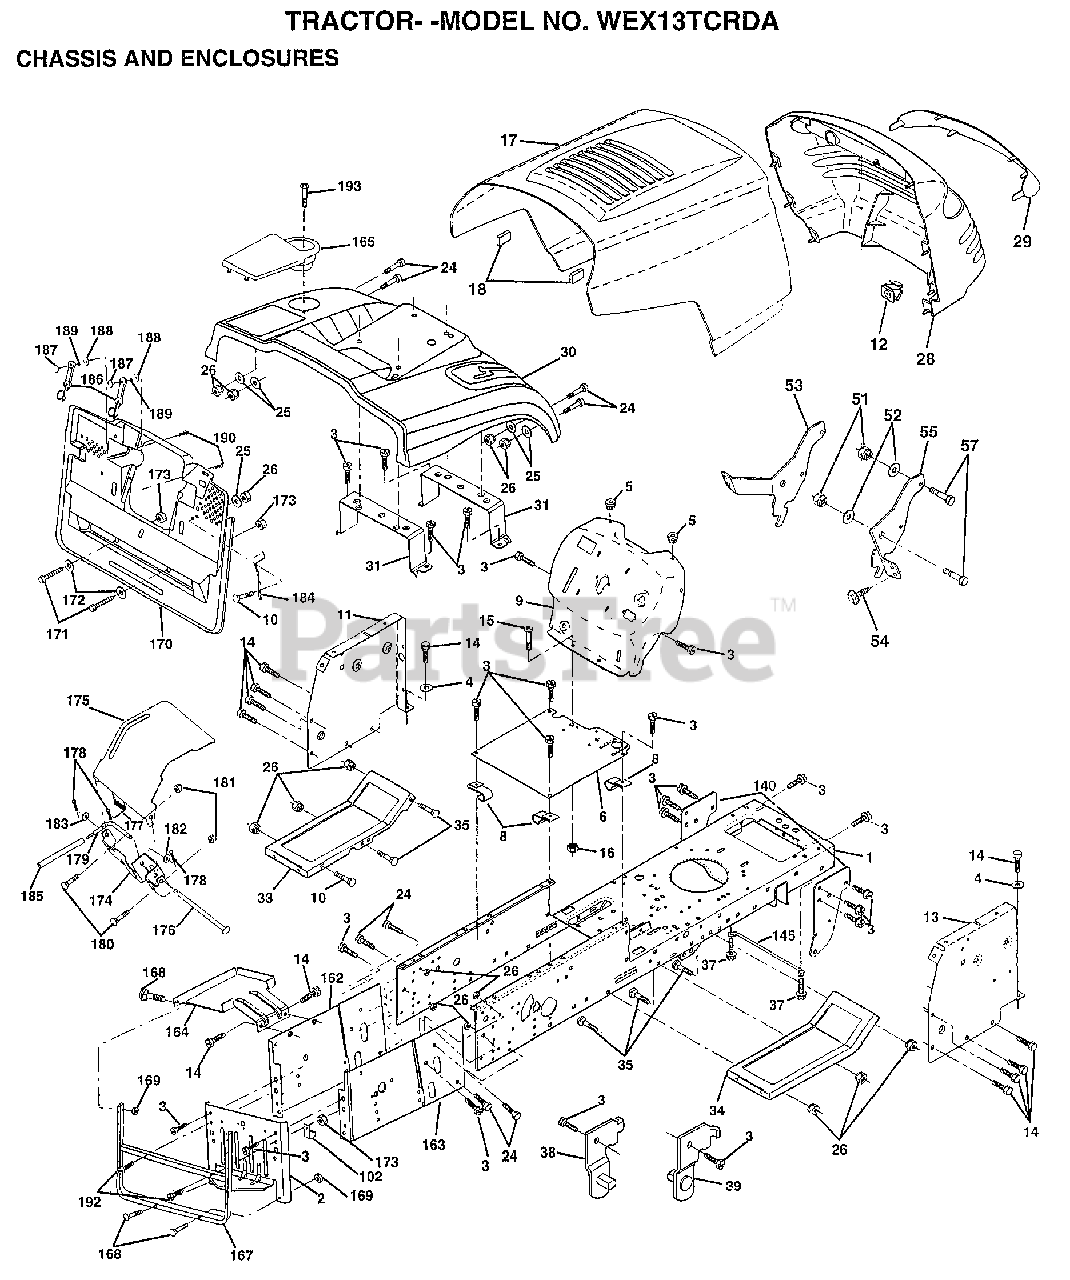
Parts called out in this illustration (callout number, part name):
1	CHASSIS.STAMPING
2	DRAWBAR.CRD
3	SCREW
4	WASHER
5	BUMPER-HOOD/DASH
6	SADDLE
8	"CLIP,INSULATOR"
9	DASH.SILKSCREEN
11	"PANEL-DASH,LH"
12	CLIP.TINNERMAN
14	SCREW LT
15	SCREW
17	HOOD.STEEL.ASSY
24	BOLT
25	WASHER
26	NUT
28	GRILLE-MS428
29	LENS.GRILLE.PRIVATE LABEL
30	FENDER.GEAR.CRD.GREEN
31	BRKT.SUPT.FENDER.CRD
33	FOOTREST.LH.LT/GT
34	FOOTREST.RH.LT/GT
35	BOLT
37	SCREW LT
38	BRACKET ASM LH
39	BRACKET ASM RH
51	NUT
52	WASHER
53	BRACKET.GRILLE.LH
54	SCREW.HEX.WS.HD
55	BRACKET.GRILLE.RH
102	CLIP T
140	BRKT SUSPENSION
145	"ROD POVOT,CHASSIS"
162	BRKT.EXT.CHASSIS.LH.CRD
163	BRKT.EXT.CHASSIS.RH.CRD
164	SUPPORT.BATTERY.CRD
165	COVER.BATTERY.CRD.BLACK.LT
167	SUPT.ASM.BACKPLATE
168	BOLT-RD HD SQ NK
170	COVER.BACKPLATE.BLACK
171	BOLT.HEX.3/8-16X2-1/2
173	NUT
174	BRKT.SWITCH.FBI.CRD
175	GRUARD.DOOR.REAR.CRD
176	HINGE PIN
177	SPRING.COVER.LH
179	ROD.PIVOT.FBI.CRD
182	WASHER.385X.625
183	WASHER
184	BRKT.ACTUATOR.BAG.CRD
185	TUBE.LEVER.SWCH.FBI.CRD
186	LATCH ASSY.BAGGER
187	WELDNUT
188	WASHER #10
189	LOCKWASHER
190	SCREW
192	SCREW LT
193	SCREW LT
